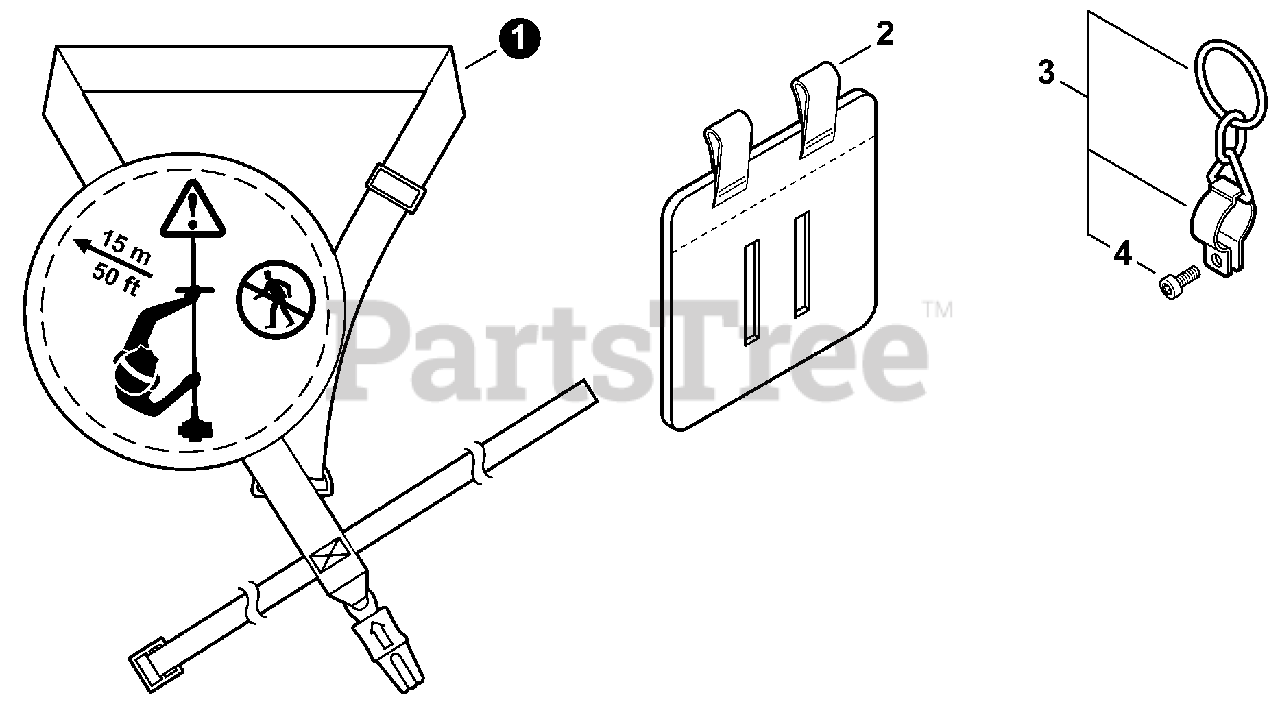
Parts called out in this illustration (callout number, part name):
1	HARNESS, SHOULDER
2	PAD, HIP
3	HANGER SET, HARNESS
4	BOLT, TORX 5×12
